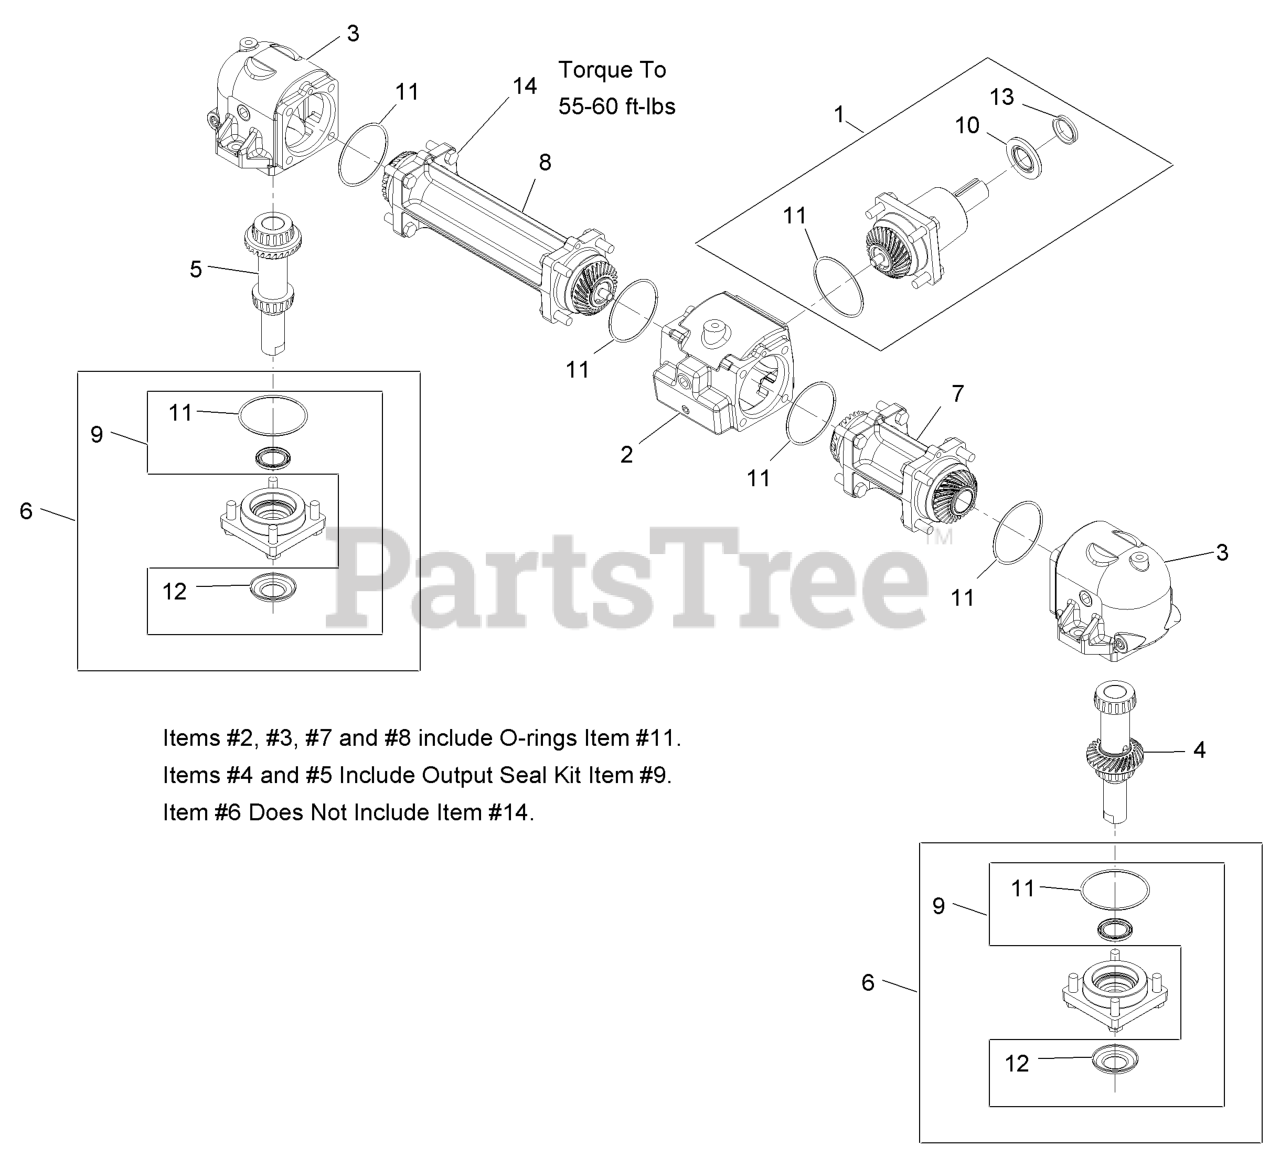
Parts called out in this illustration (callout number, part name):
1	INPUT PINION ASM
1	PINION-INPUT
2	HOUSING-CENTER
3	HOUSING-END
4	LH OUTPUT SHAFT AND GEAR
5	RH OUTPUT SHAFT AND GEAR
6	CAP-OUTPUT
7	TUBE-CONNECTOR, SHORT
8	TUBE-CONNECTOR, LONG
9	OUTPUT SEAL KIT
10	SEAL-INPUT
11	SEAL-O-RING
12	WASHER-CUPPED
13	SEAL-V-RING
